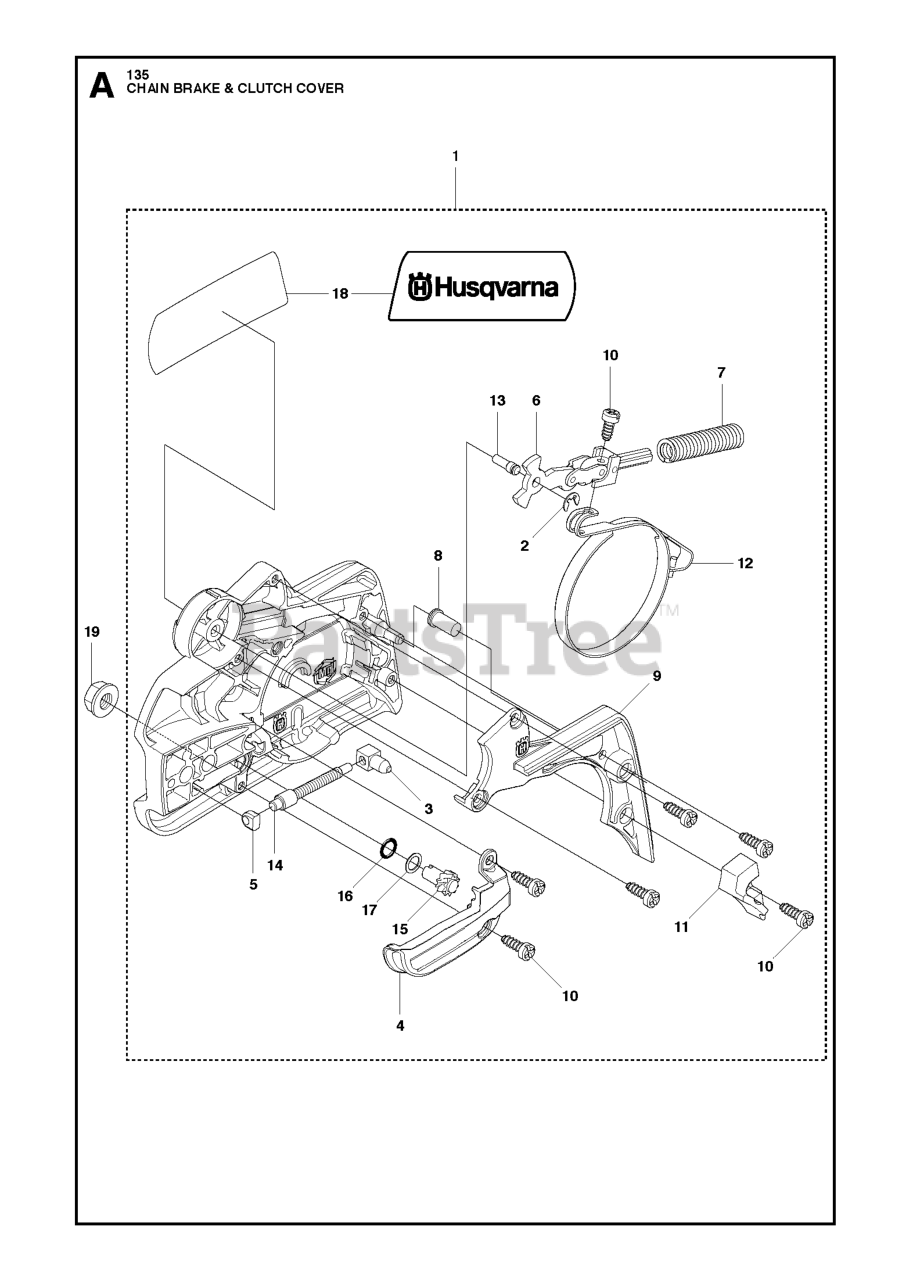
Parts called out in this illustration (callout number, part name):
1	CLUTCH COVER ASSY
2	E-RING 4
3	PAWL
4	CHAIN GUIDE
5	SLEEVE
6	JOINT
7	BRAKE SPRING
8	SLEEVE
9	COVER
10	SCREW
11	WEAR PROTECTION
12	BRAKE BAND ASSY
13	PIN
14	SCREW
15	WORM WHEEL
16	O-RING
17	WASHER
18	LABEL 400 SERIES
19	NUT M8 FLANGE
